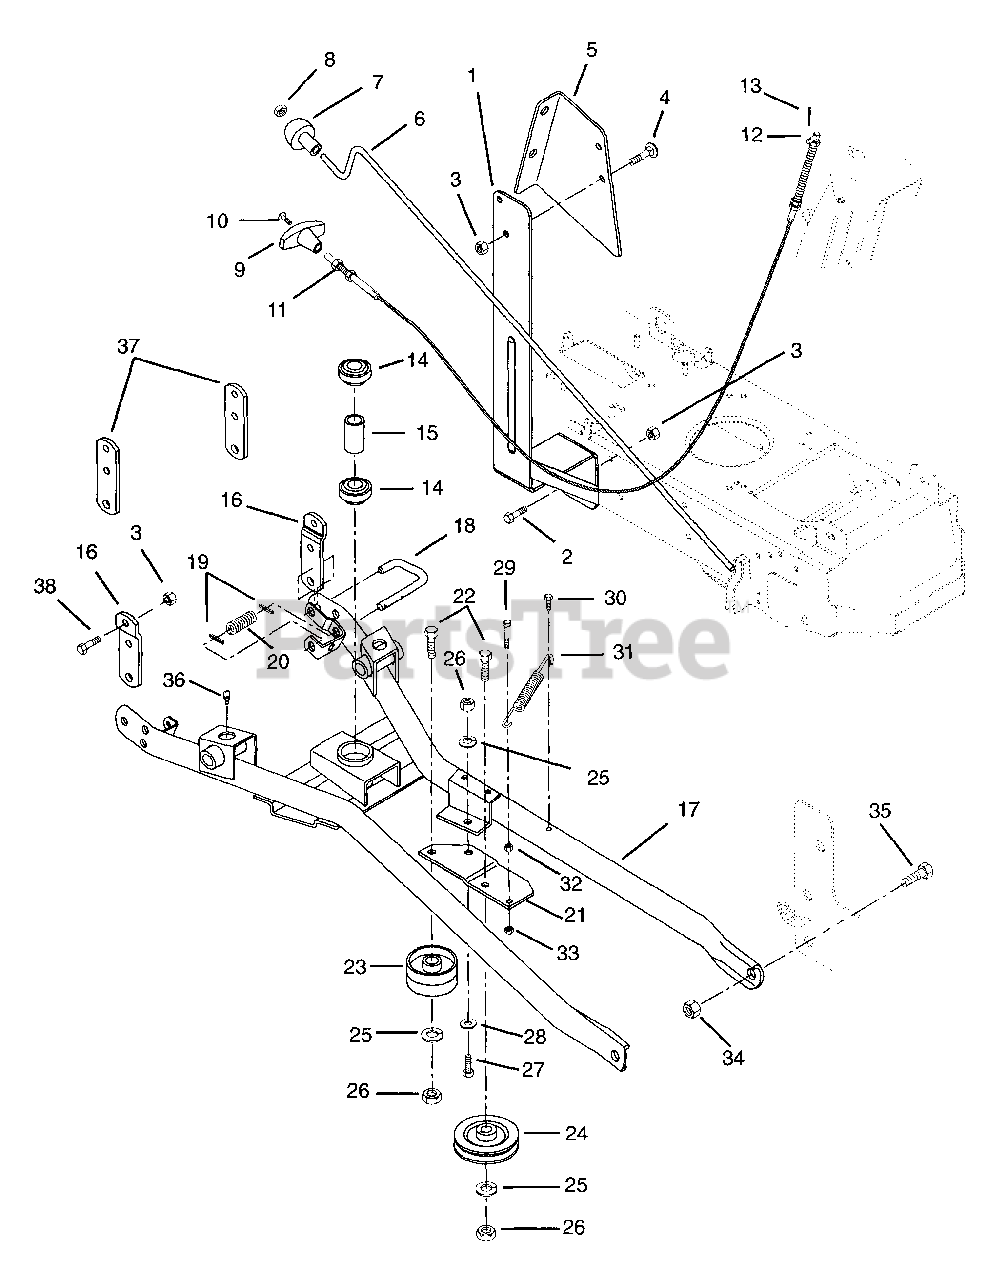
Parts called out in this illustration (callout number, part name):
1	SUPPORT - CONTROL BRACKET
2	@BLT-HEX .38-16X.75 GR5 YWZC
3	@NUT-LK-CTR .38-16 YWZC
4	BLT-RDHDSQNK .375-16X.75 GR5PL
5	CONTROL BRACKET
6	CHUTE CONTROL CRANK
8	@NUT-LK-CTR-JAM .375-16 YWZC
9	KNOB-BLACK
10	SCR-MCH 8-32X.75 PN HD YWZC
11	CONTROL CABLE
13	@PIN-CTR .09X.75 EXTPRSQCT YWZ
14	BRG-BALL .750X1.781X.61
15	SPACER .765X1.000X1.252
16	HANGER BRACKET- OFFSET
17	CARRIAGE FRAME W/ SPINDLE&BRGS
18	LATCH PIN
19	PIN-ROLL .125X.75
20	SPRG, COMP .058X.65X2.13 WLD15
21	IDLER ARM
22	@BLT-HEX .38-16X1.75 GR5 YWZC
23	IDLER-FLAT 2.25 X .38
24	IDLER-V 3.06 X .38
25	@WSHR-LK .38X.094 REG YWZC
26	@NUT-HEX .38-16 YWZC
27	SHOULDER BOLT .50 X .281
28	WSHR-FL-STL.511X1.441X.125 YWZ
29	SCR-TAP 10-24X1.0 HWH PL TR
30	@SCR-TAP .31-18X.75 HWH TR YWZ
31	SG-TENS .090X.75X3.50 WLD 34
32	@NUT-HEX 10-24 YWZC
33	@NUT-LK-NYL 10-24 W/INSRT YWZC
34	@NUT-LK-CTR .62-11 YWZC
35	@BLT-HEX .62-11X1.50 GR5 YWZC
36	FTG-LUBE .25-28X.256 YWZC
37	HANGER BRACKET
38	@BLT-HEX .38-16X1.00 GR5 YWZC
